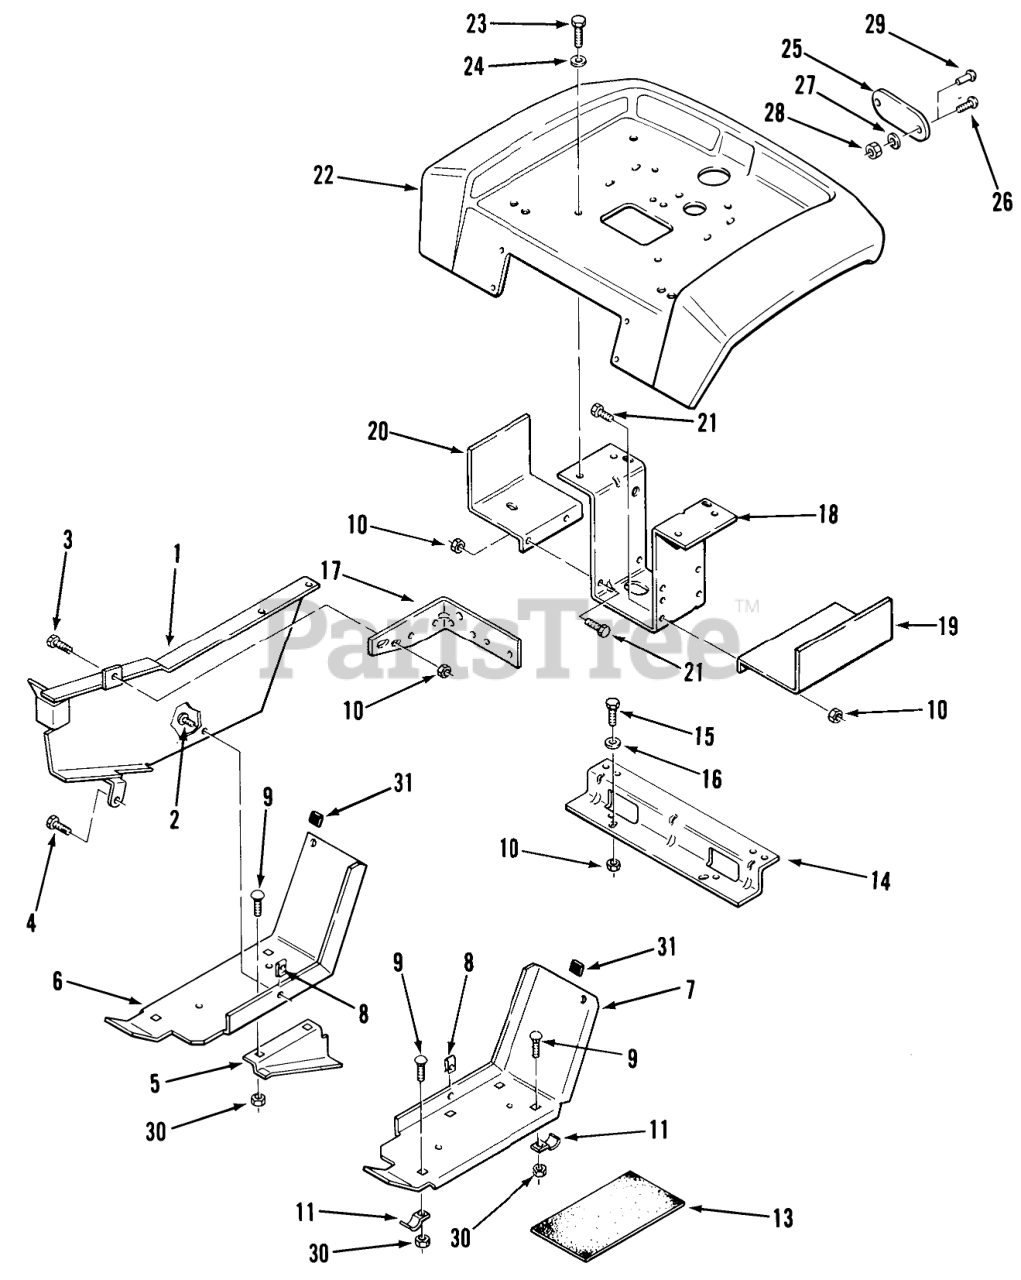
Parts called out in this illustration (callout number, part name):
4	SCREW
7	FOOTREST LH *R
11	BRACKET
13	RH FOOTREST MAT
13	PAD-FOOTREST
13	PAD FOOTREST
16	WASHER 5/16 SAE
23	S.T. Bolt 5/16-18 x 5/8
24	WASHER 5/16 SAE
31	BUMPER
